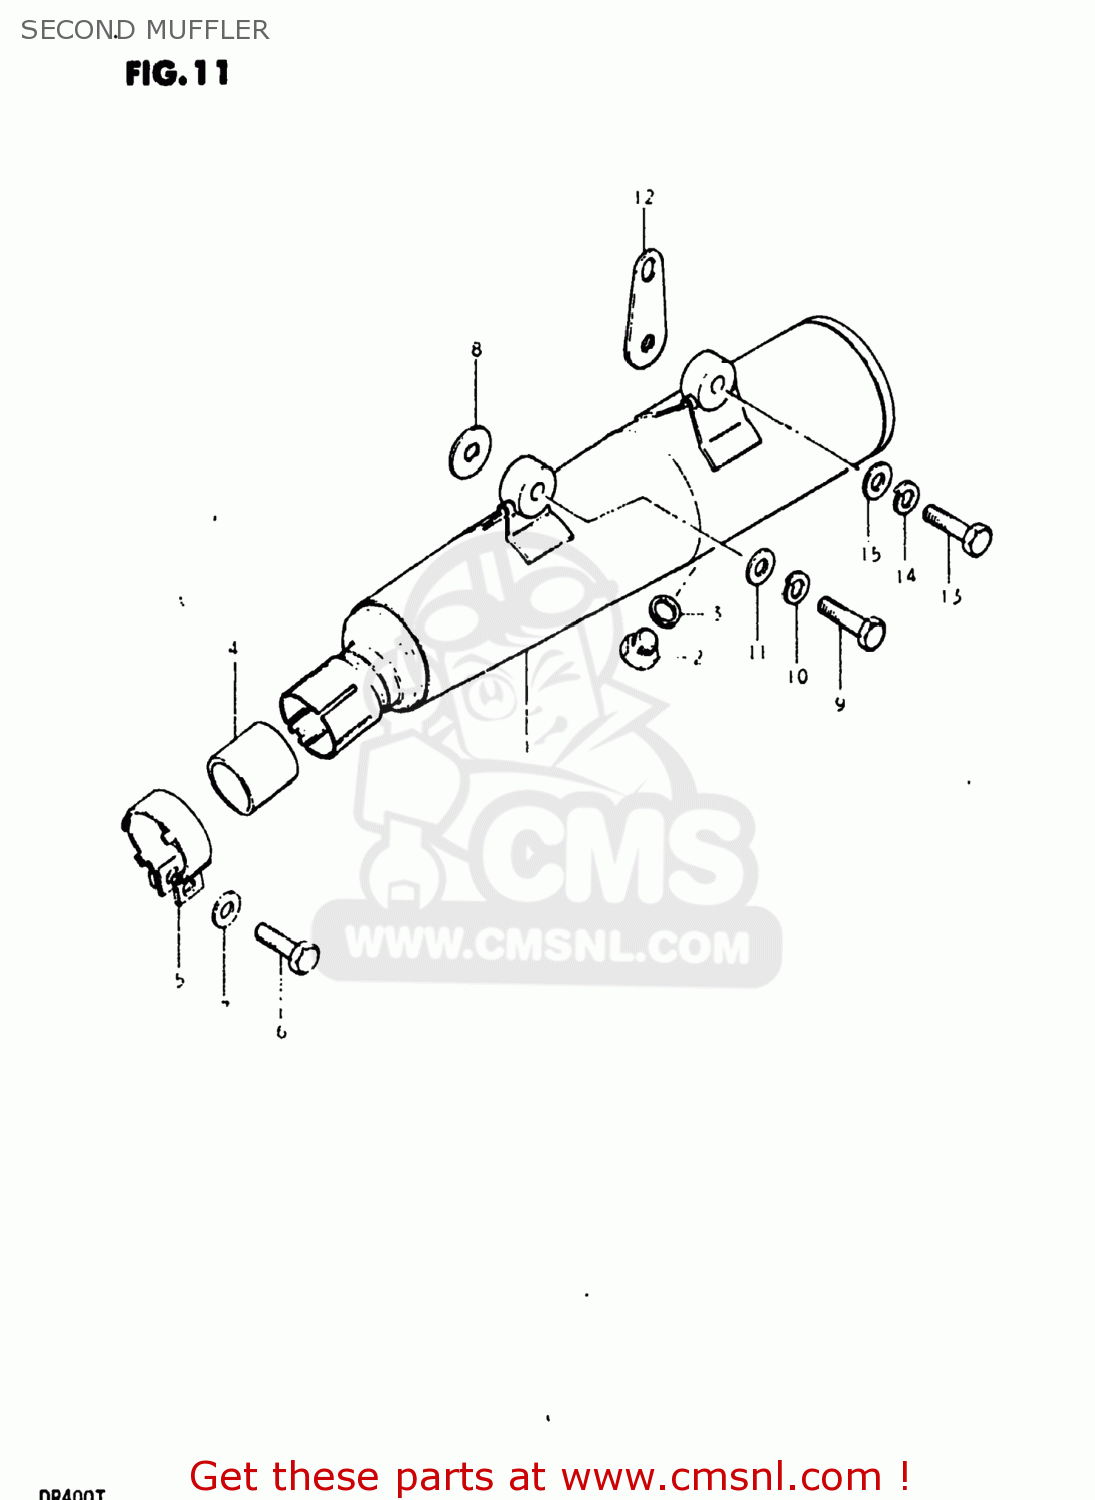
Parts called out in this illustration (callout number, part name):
1	MUFFLER ASSEMBLY
2	PLUG(12X9)
3	GASKET(12X16X2) (NAS)
4	CONNECTOR,MUFFLER
5	CLAMP,MUFFLER CONNECTOR
6	BOLT(8X14)
7	WASHER
8	WASHER (8.5X29X1.6)
9	BOLT
10	LOCK WASHER
11	WASHER
12	BRACE,MUFFLER
13	BOLT
14	LOCK WASHER
15	WASHER
